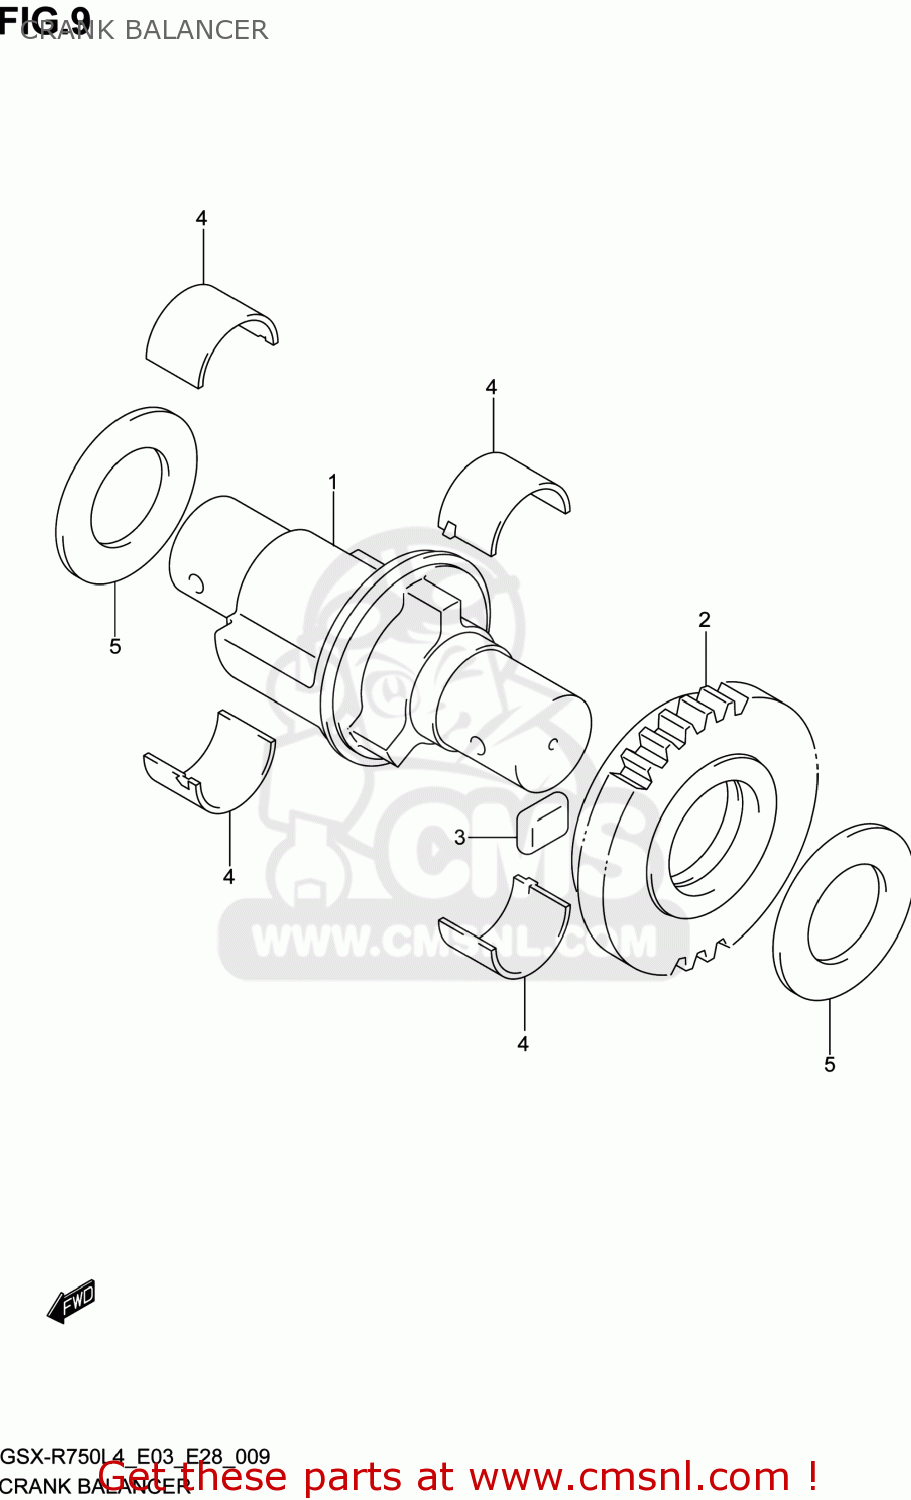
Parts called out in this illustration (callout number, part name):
1	BALANCER,CRANK
2	GEAR,CRANK BALANCER
3	DAMPER,CRANK BALANCER GEAR
4	BEARING,CRANK BALANCER
5	SHIM(23X40X2)
